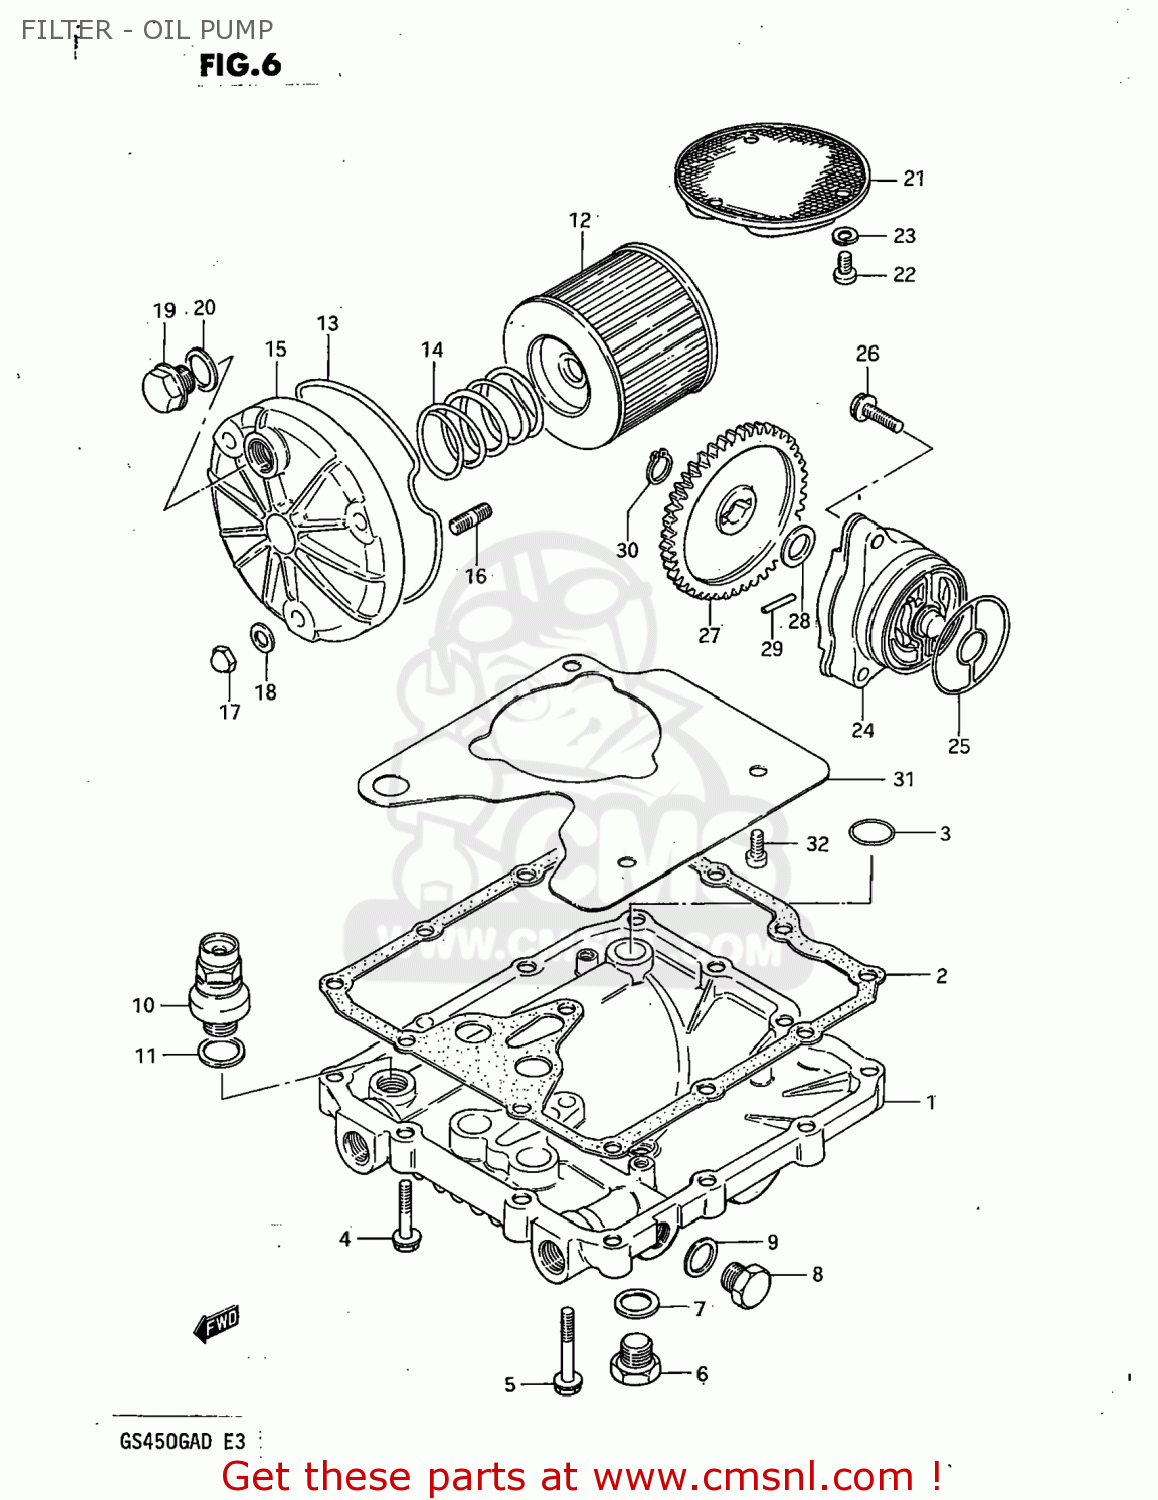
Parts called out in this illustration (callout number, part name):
1	PAN,OIL
2	GASKET,OIL PAN (MCA)
3	O RING(D:3.2,ID:12.9)
4	BOLT
5	BOLT 6X35
6	PLUG
7	GASKET(14X19.2X2) (NAS)
8	PLUG(12X9)
9	GASKET(12.1X16.2X3.7) (NAS)
10	REGULATOR ASSY,ENGINE OIL
11	WASHER
12	FILTER ASSY,ENGINE OIL
13	O RING,OIL FILTER CHAMBER CAP
14	SPRING
15	CAP,OIL FILTER
16	STUD 6X20
17	NUT
18	WASHER
19	PLUG
20	GASKET(14X19.2X2) (NAS)
21	STRAINER,ENGINE OIL
22	SCREW 6X12
23	LOCK WASHER
24	PUMP ASSEMBLY,OIL
25	O-RING,OIL PUMP
26	BOLT(6X32)
27	GEAR,OIL PUMP DRIVEN
28	SHIM
29	PIN(4X15.8)
30	CIRCLIP
32	SCREW 6X12
